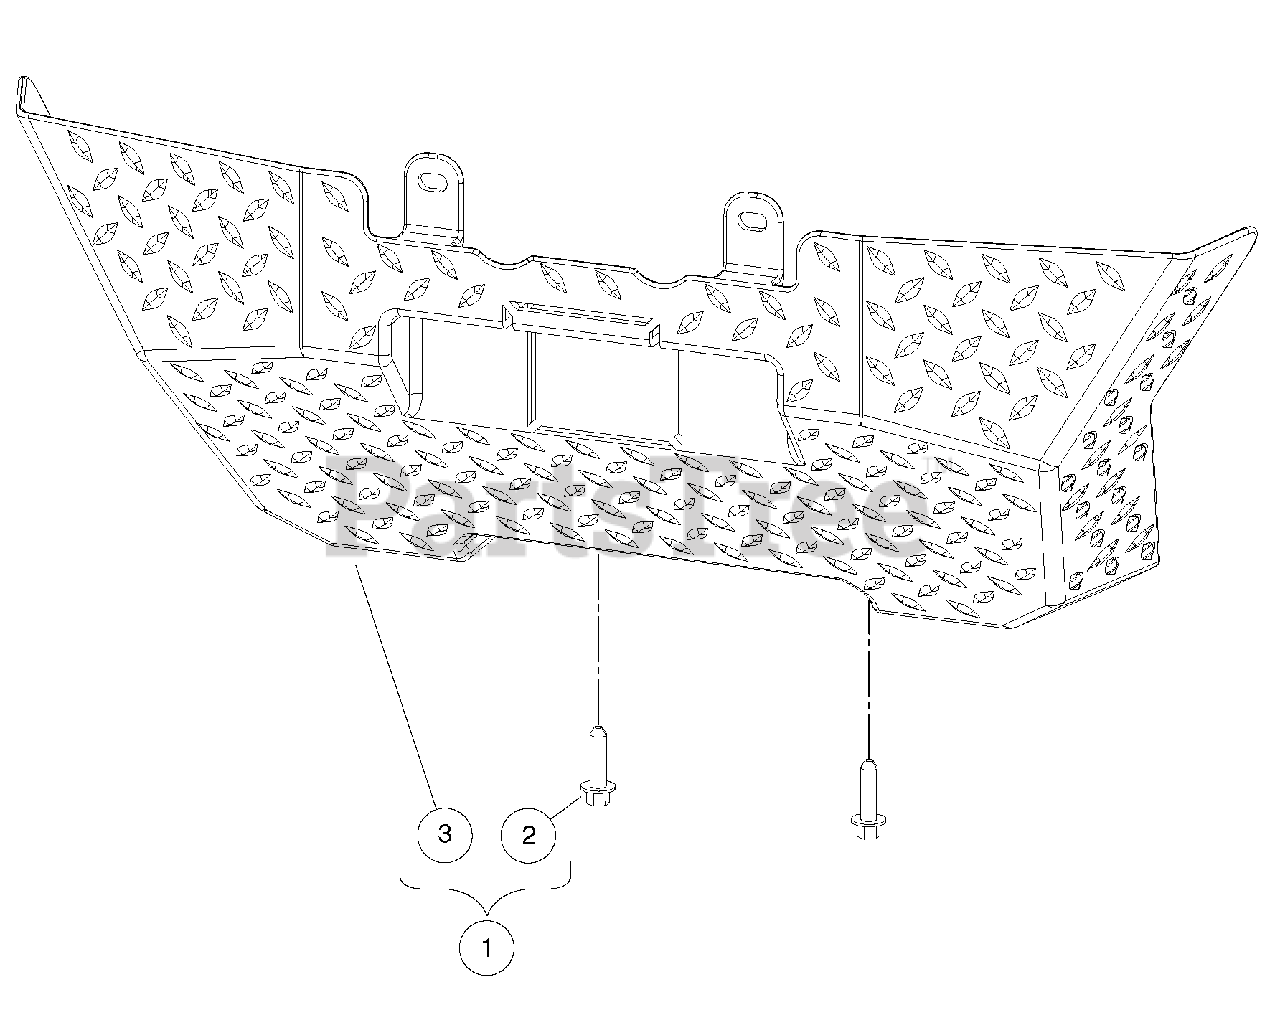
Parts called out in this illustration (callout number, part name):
1	Instl, Skid, Std
2	Screw, M8X1.25X30, Hex
3	Plate, Skid, Std
